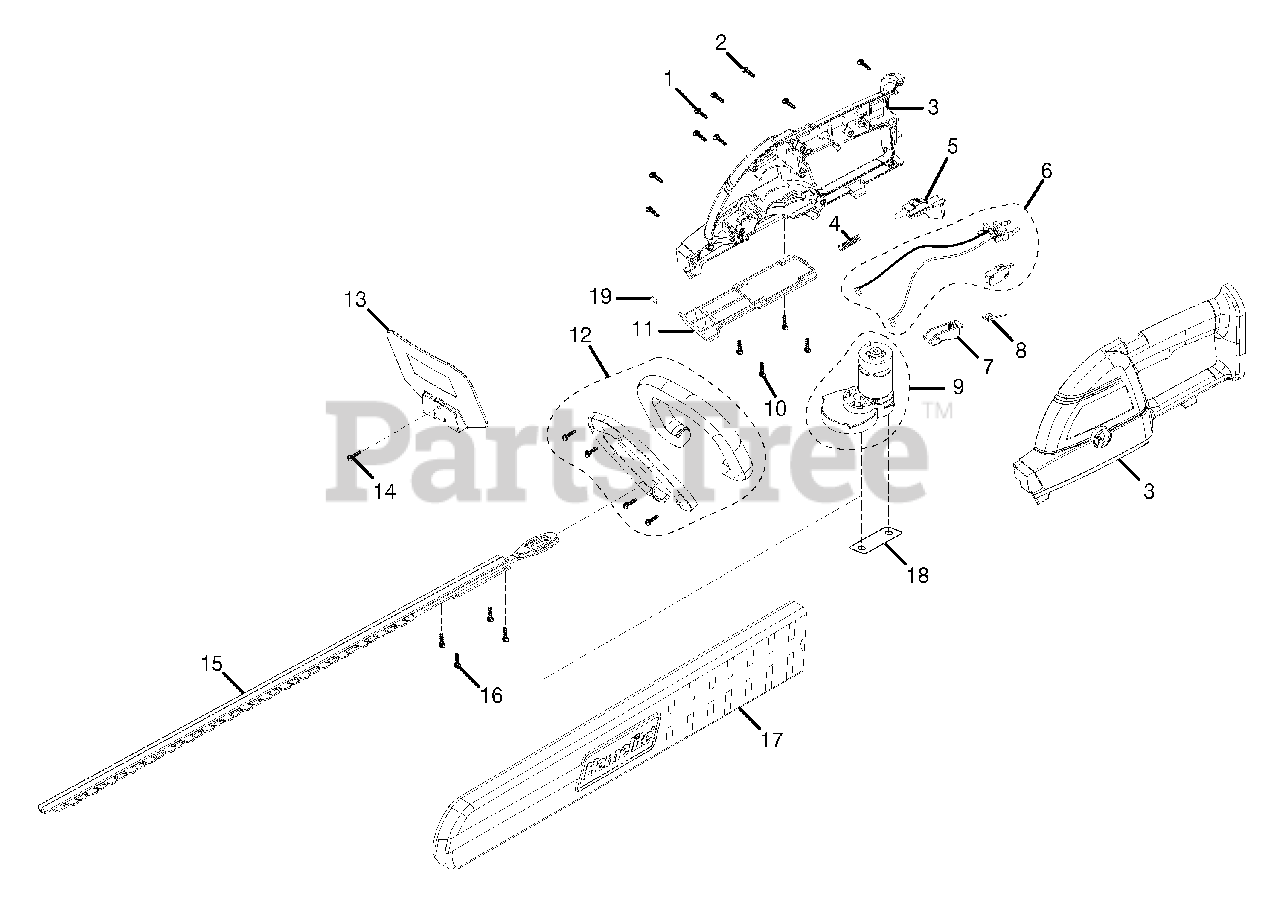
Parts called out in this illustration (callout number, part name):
1	SCREW (M4 X 22 mm PAN HD)
2	SCREW (M4 X 16 mm PAN HD)
3	HOUSING ASSEMBLY
5	TRIGGER LOCK BUTTON
6	SWITCH ASSEMBLY
8	TRIGGER SPRING
9	MOTOR AND GEAR TRAIN ASSEMBLY
10	SCREW (M4 X 12 mm)
11	BOTTOM PLATE
12	HANDLE ASSEMBLY
13	BLADE GUARD
14	SCREW (M4 X 16 mm)
15	BLADE ASSEMBLY
16	BLADE SCREW (M4 X 16 mm)
17	BLADE COVER
18	BAR PLATE
19	SPONGE SEAL
